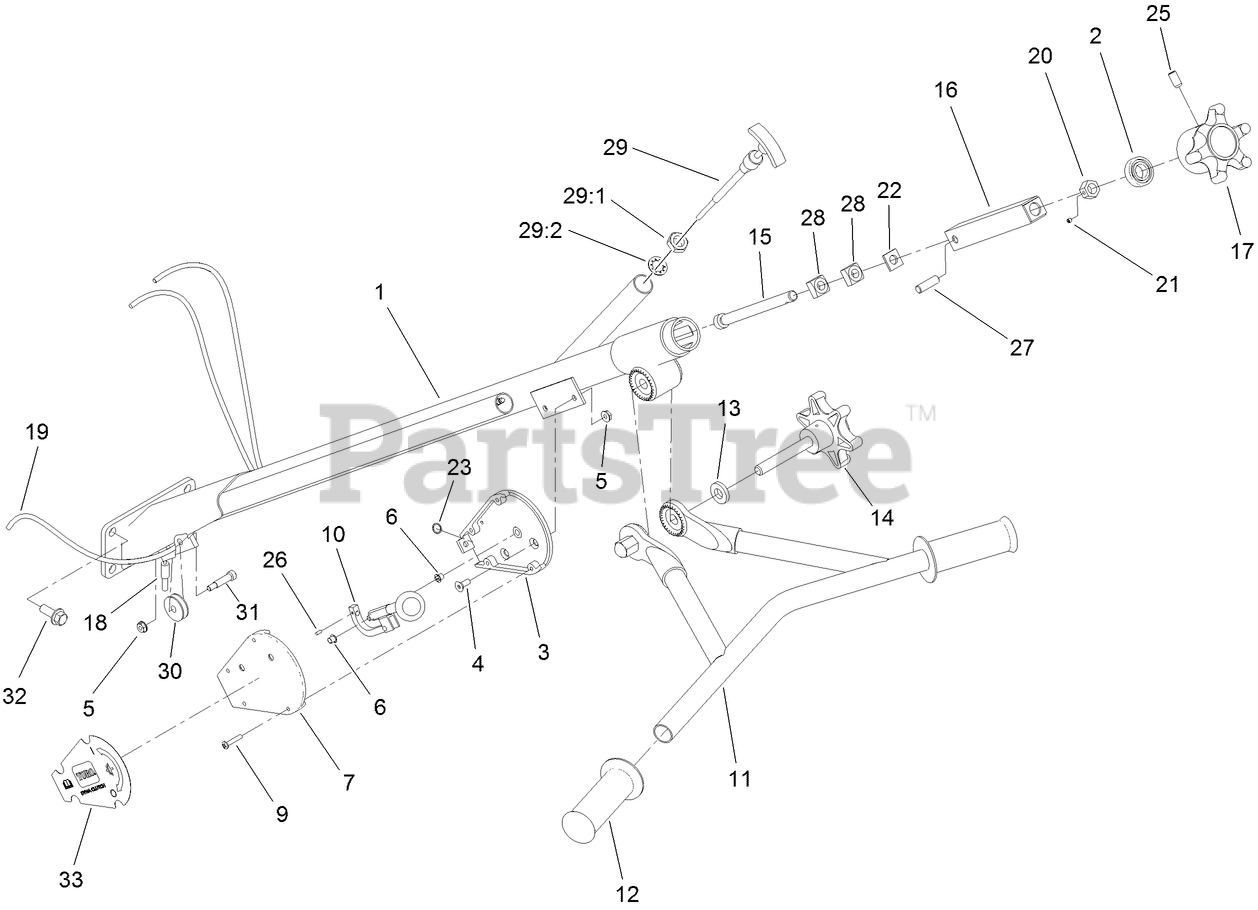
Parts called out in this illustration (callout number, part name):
1	HANDLE-MAIN
2	BEARING-BALL
3	HOUSING-CLUTCH
4	SCREW-HSFH
5	NUT-KEPS
6	BUSHING-FLANGE
7	COVER-CLUTCH
9	SCREW-PPH
10	LEVER ASM
11	HANDLE-ADJUSTABLE
12	GRIP-HANDLE
13	WASHER-FLAT
14	KNOB-ADJUSTMENT
15	ROD-TILT
16	BLOCK-TILT
17	HANDLE-TILT, BLADE
18	CABLE-TILT
20	NUT-LOCK, TILT
21	SCREW-HSH, SET
22	WASHER-SQUARE
23	RING-EXTERNAL
25	SCREW-HSH, SET
28	NUT-SQUARE
29	CABLE ASM
29:1	NUT-JAM
29:2	WASHER-LOCK
30	PULLEY-PIVOT
31	SCREW-HSBH
32	SCREW-HHF
